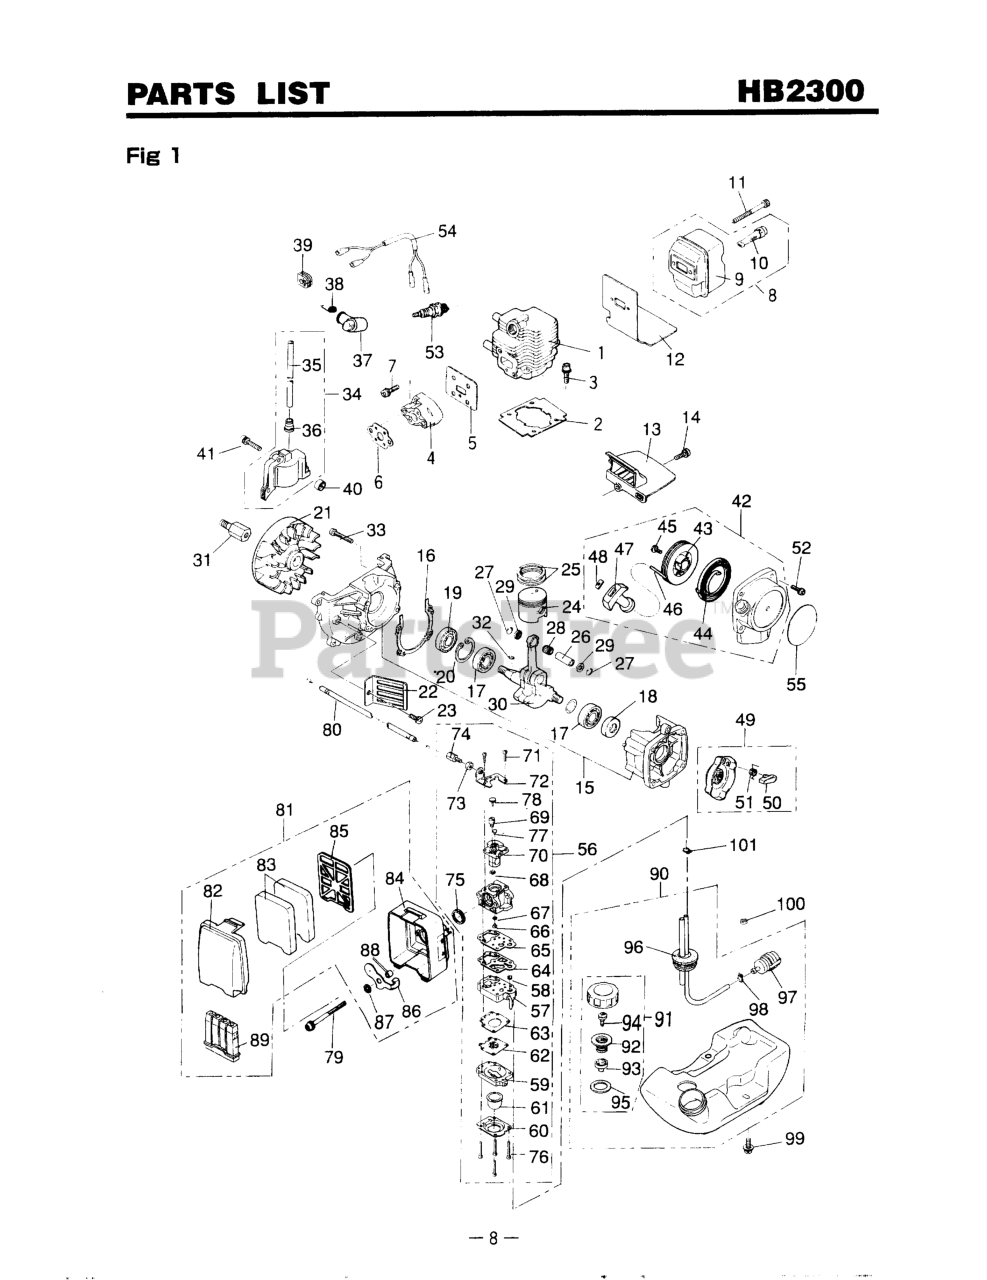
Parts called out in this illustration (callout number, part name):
1	CYLINDER
3	BOLT, M5 X 22
7	SCREW, M5X20 (RPLS.1400-75510)
10	ARRESTER (RPLS 5850-15140)
11	BOLT
12	GASKET
14	SCREW, M4 X 16
15	CRANKCASE
17	BEARING
18	SEAL, OIL (RPLS 1100-21210)
19	SEAL, OIL (RPLS 1140-21220)
20	RING, SNAP, M28 x 1.2
21	BOLT, M5 X 30
23	SCREW,M5 X 14 (RPLS 1400-15510
24	PISTON (REPLACES 1140-41110)
25	RING, PISTON (RPLS 1850-41210)
26	PIN, PISTON 5x8x26
27	RING, SNAP (RPLS 1101-41320)
29	WASHER
30	CRANKSHAFT (RPLS 1850-42000)
31	EXTENSION
32	KEY
35	CORD
36	CAP
38	SPRING
39	GROMMET
41	BOLT
42	RECOIL ASSEMBLY
43	REEL
44	SPRING, SPIRAL
45	SCREW (RPLS -75150)
47	KNOB
48	PLATE, STOPPER
49	PULLEY ASSY (RPLS -75210)
50	RATCHET (RPLS 1850-75220)
51	SPRING, RETURN
52	SCREW, M4 X 16
54	CORD COMPLETE
55	LABEL (USE -75611)
56	CARBURETOR
57	BODY, PUMP
59	BODY, PURGE
60	COVER, PUMP
61	PUMP, PRIMING
62	DIAPHRAGM (USE 4810-81260)
63	GASKET, DIAPHRAGM
64	DIAPHRAGM
65	GASKET, PUMP
66	JET
67	RING, O
68	RING
69	SWIVEL
70	VALVE ASSEMBLY
71	SCREW
73	NUT, CABLE ADJUSTER
74	SCREW, CABLE ADJUSTER
75	RING, PACKING
76	SCREW
77	WASHER
79	SCREW, M5 x 60
80	CABLE (USE -83101)
82	COVER
83	FILTER
84	HOUSING
85	PLATE
86	VALVE, CHOKE
87	WASHER
88	SLEEVE (REPLACES 1750-82060)
89	SILENCER
93	HOLDER, CAP
94	VALVE (NLA WHEN OUT)
95	PACKING
96	PIPE COMPLETE
97	FILTER ASSY
98	CLIP (REPLACES 2841-31280)
99	SCREW (REPLACES 4500-13180)
100	COLLAR (USE -85531)
101	CLIP
